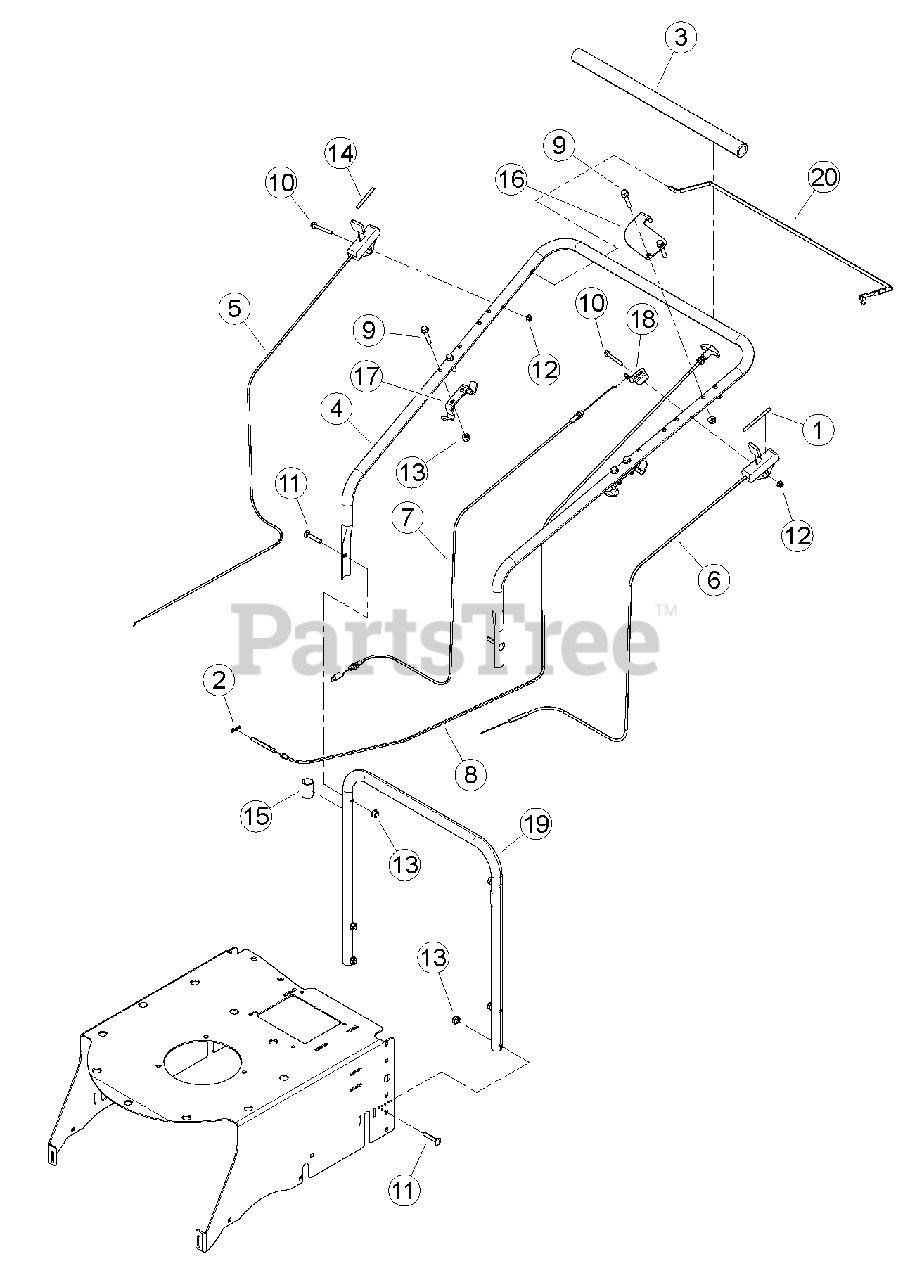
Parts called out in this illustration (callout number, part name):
1	DECAL, 3 SPEED
2	CLIP, HAIRPIN ZP
3	PAD, FOAM HANDLEBAR
4	HANDLEBAR, BEARVAC UPPER
5	CONTROL, THROTTLE
6	CONTROL, TRANSMISSION SHIFT
7	CONTROL, CLUTCH ENGAGEMENT
8	CONTROL, HEIGHT ADJUSTMENT
9	BOLT, 5/16 X 1-3/4 FLANGE NC
10	BOLT, 1/4 X 2 FLANGE NC
11	BOLT, 5/16 X 1-3/4 GR5 CRG ZP
12	NUT, 1/4-20 NYLOCK-FLANGE
13	NUT, 5/16-18 NYLOCK-FLANGE
14	DECAL, THROTTLE
15	CAP, 7/8" PLASTIC
16	BRACKET, BEARVAC CABLE MOUNT
17	BRACKET, BAG HANGER
18	BRACKET, CLUTCH CABLE
19	HANDLEBAR, LOWER BEARVAC
20	BAIL, BEARVAC CLUTCH CONTROL
